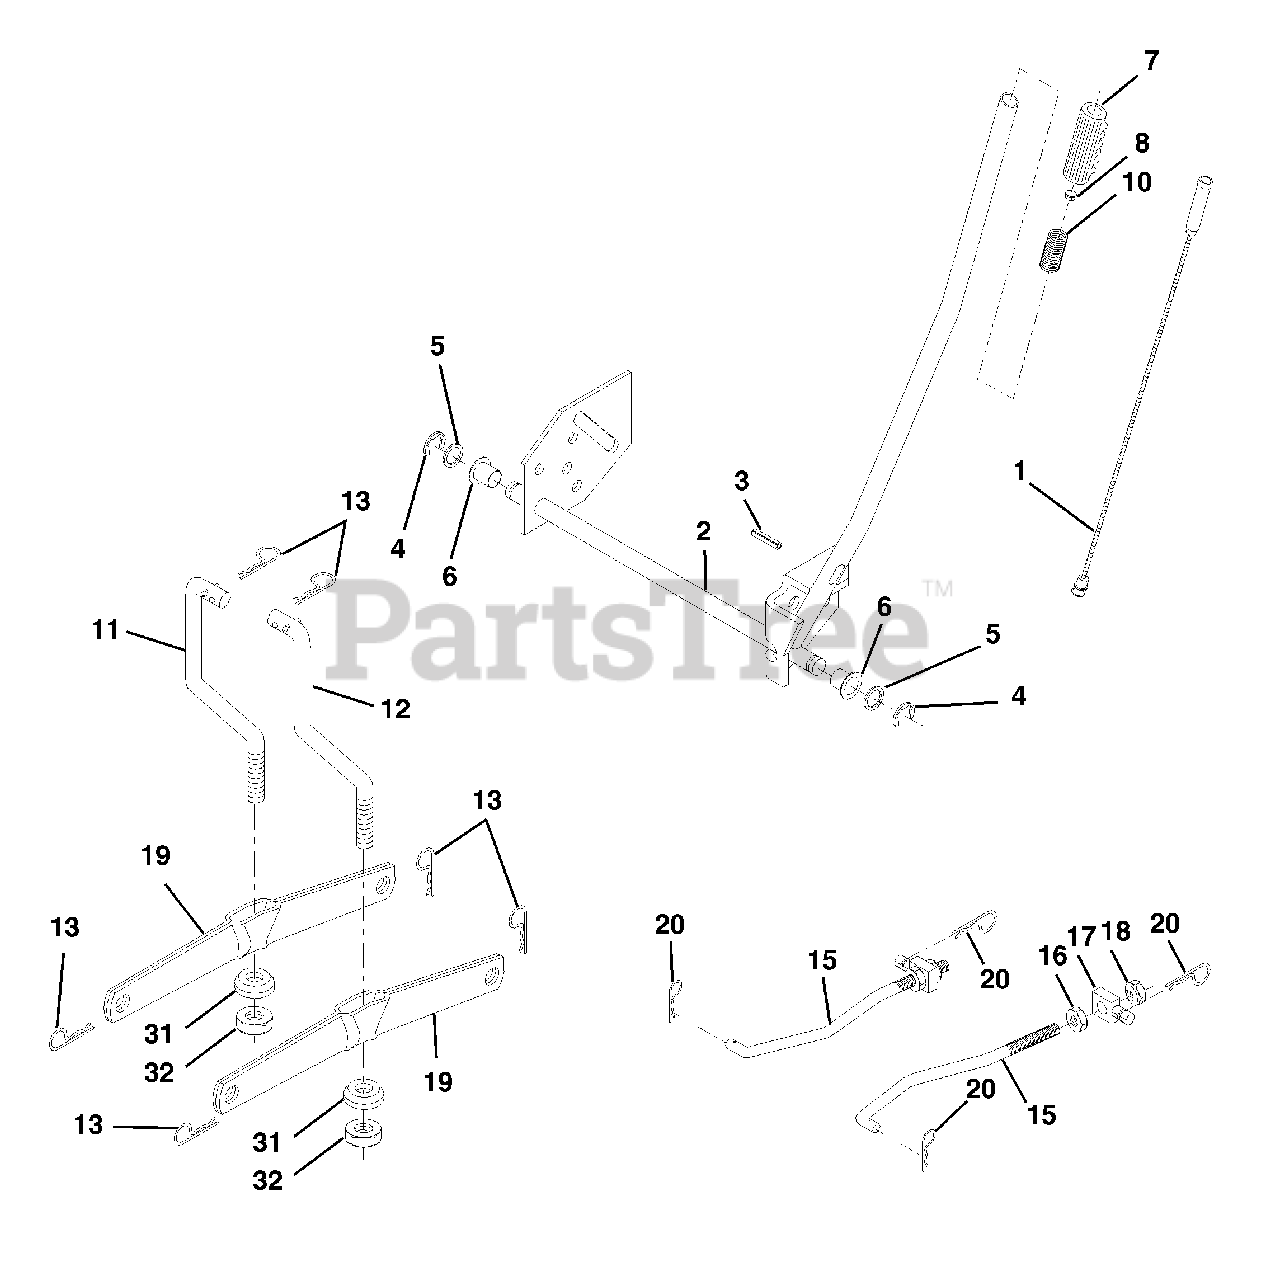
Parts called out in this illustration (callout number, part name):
1	Wire Asm Inner W/plunger 17 32
2	Shaft Asm Lift
3	Pin Groove
4	E Ring #5133-62
5	Washer PLTD 21/32 X 1 X 21ga
6	Bearing Nylon Blk 629 Id
7	Grip Handle Bicycle
8	Button Plunger Black
11	Link Lift LH
12	Link Lift RH
13	Retainer Spring
15	Link Front
16	Nut Jam Hex 1/2-13 Unc
17	Trunnion Blk Zinc
18	Nut Lock W/wsh 1/2-13unc
19	Arm Suspension Rear
20	Spring, Retainer
31	Bearing Pvt. Lift Spherical
32	Nut Crownlock 3/8-24
